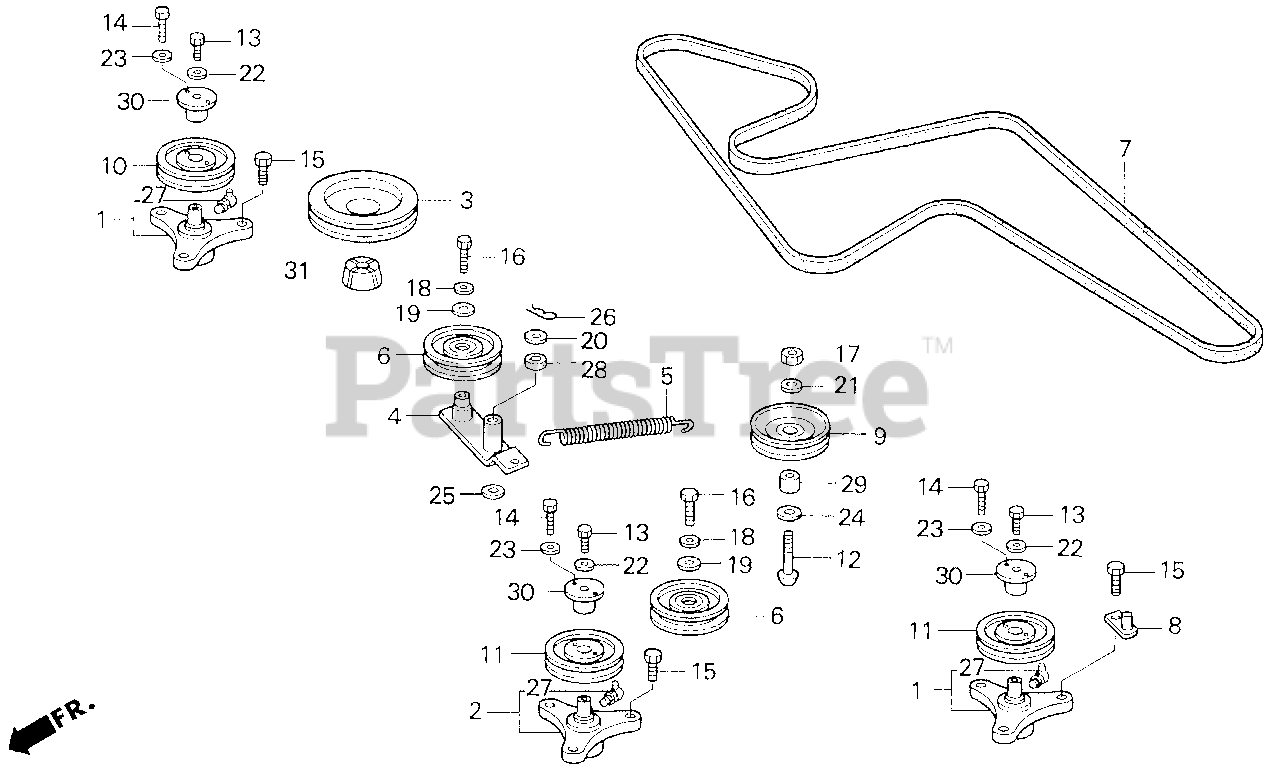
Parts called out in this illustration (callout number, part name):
1	HOUSING ASSY., BEARING
2	SPINDLE ASSY., CENTER
3	PULLEY, DRIVE
4	ARM, TENSION
5	SPRING ASSY.
5	SPRING, TENSIONER ARM
6	ROLLER, TENSIONER
7	V-BELT, BLADE
8	STOPPER, BELT
9	PULLEY, IDLER
10	PULLEY, R. BLADE
11	PULLEY, L. BLADE
12	BOLT (5/8X2-1/2)
13	BOLT (1/4 NCX1/2 HHCS)
14	BOLT (1/4 NCX1 HHCS)
15	BOLT (1/2NF HHCS)
16	BOLT, TENSIONER
17	NUT (5/8 NC HEX. LOCK)
18	WASHER (3/8 STD LOCK)
19	WASHER, TENSIONER ARM
20	WASHER (5/8X1-1/8X0.095)
21	WASHER, FLAT (5/8)
22	WASHER, FLAT (1/4X7/8X7GA)
23	WASHER, LOCK (1/4)
24	WASHER, SAE FLAT (7/8)
25	WASHER (5/8X1-1/16X10GA)
26	PIN, LOCK (19MM)
27	NIPPLE, GREASE (NOT AVAILABLE)
28	DUST SEAL (5/8X1X1/4)
29	COLLAR (5/8X1X43/64)
30	BUSH, PULLEY SETTING
31	BUSH ASSY., TAPER LOCK (3/4)
